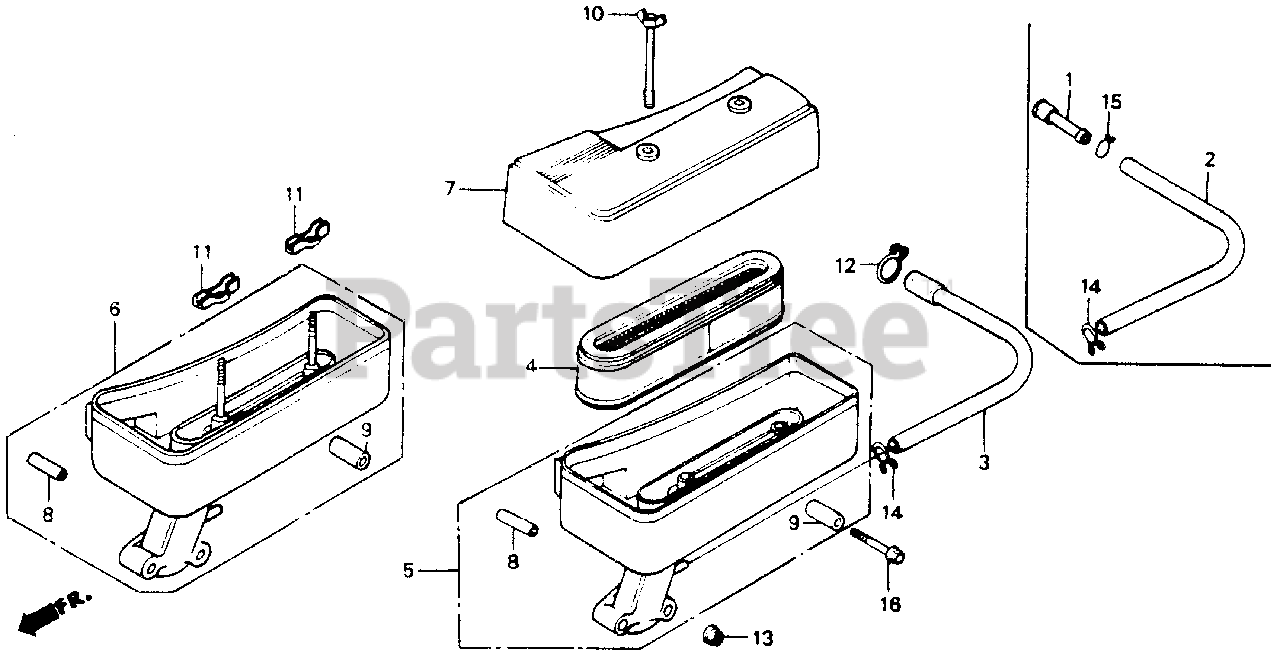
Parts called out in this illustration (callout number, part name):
3	TUBE, BREATHER
4	ELEMENT, AIR CLEANER
5	CASE SET, AIR CLEANER
6	HOUSING, AIR CLEANER
7	COVER, AIR CLEANER
8	COLLAR, AIR CLEANER
9	COLLAR B, AIR CLEANER
10	BOLT, ELEMENT SETTING
11	WINGNUT (6MM)
12	CLIP, TUBE
13	NUT, FLANGE (6MM)
14	CLIP, TUBE (B12)
16	BOLT, FLANGE (6X35)
